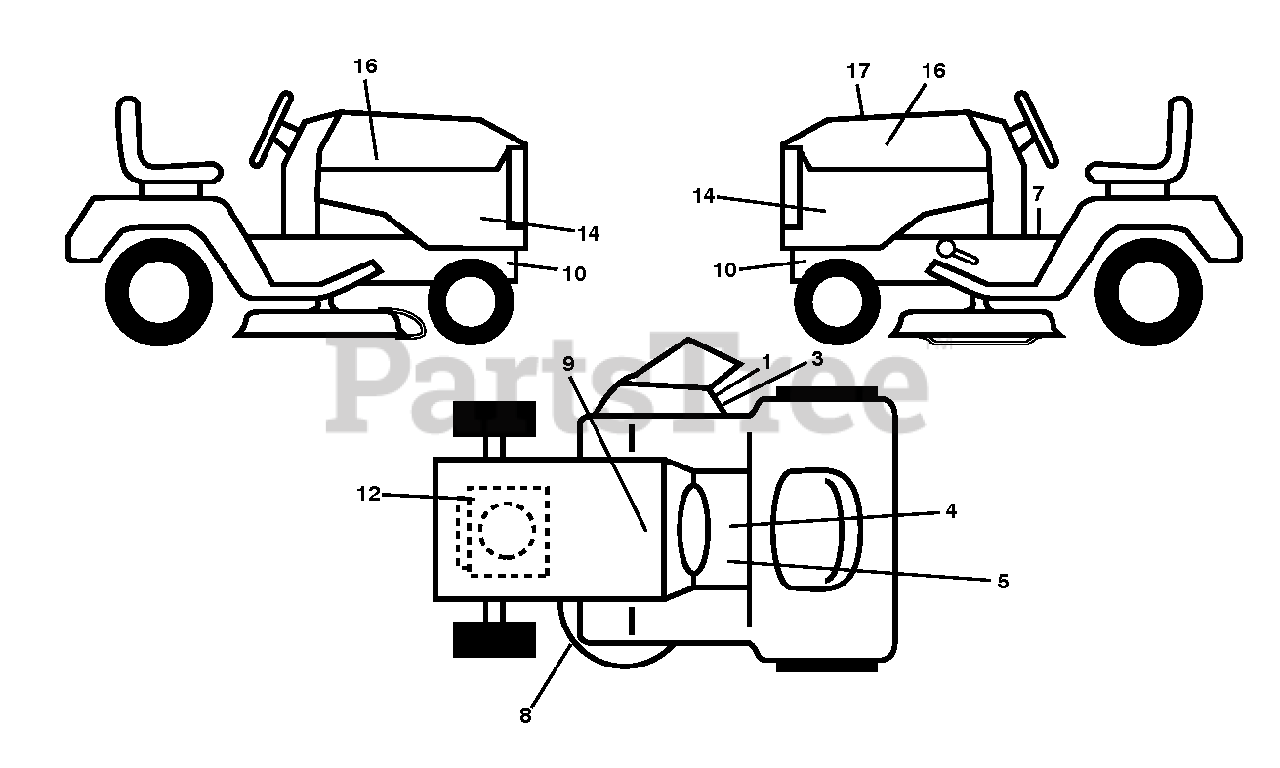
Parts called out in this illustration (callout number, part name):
1	DECAL.CUTFINGER.CE.02
3	DECAL.DFLCTR.WARNNG.CTFNGR.SYM
4	DECAL.PARKING.BRAKE.SADDLE.LT
5	DECAL.READ.OWN.MAN.SYMBOL.LT
7	DECAL.FNDR.SDLE.BRAKE.CLUTCH.6
8	DECAL.V-BELT.SCH.42/46"MEC/ELE
9	DECAL BTRY SYMBOLS
10	DECAL.CHASSIS.HOT.MUFFLER
12	DECAL.ENGINE.WARNING
16	DECAL.BADGE.170MM.TEXTLOGO.
